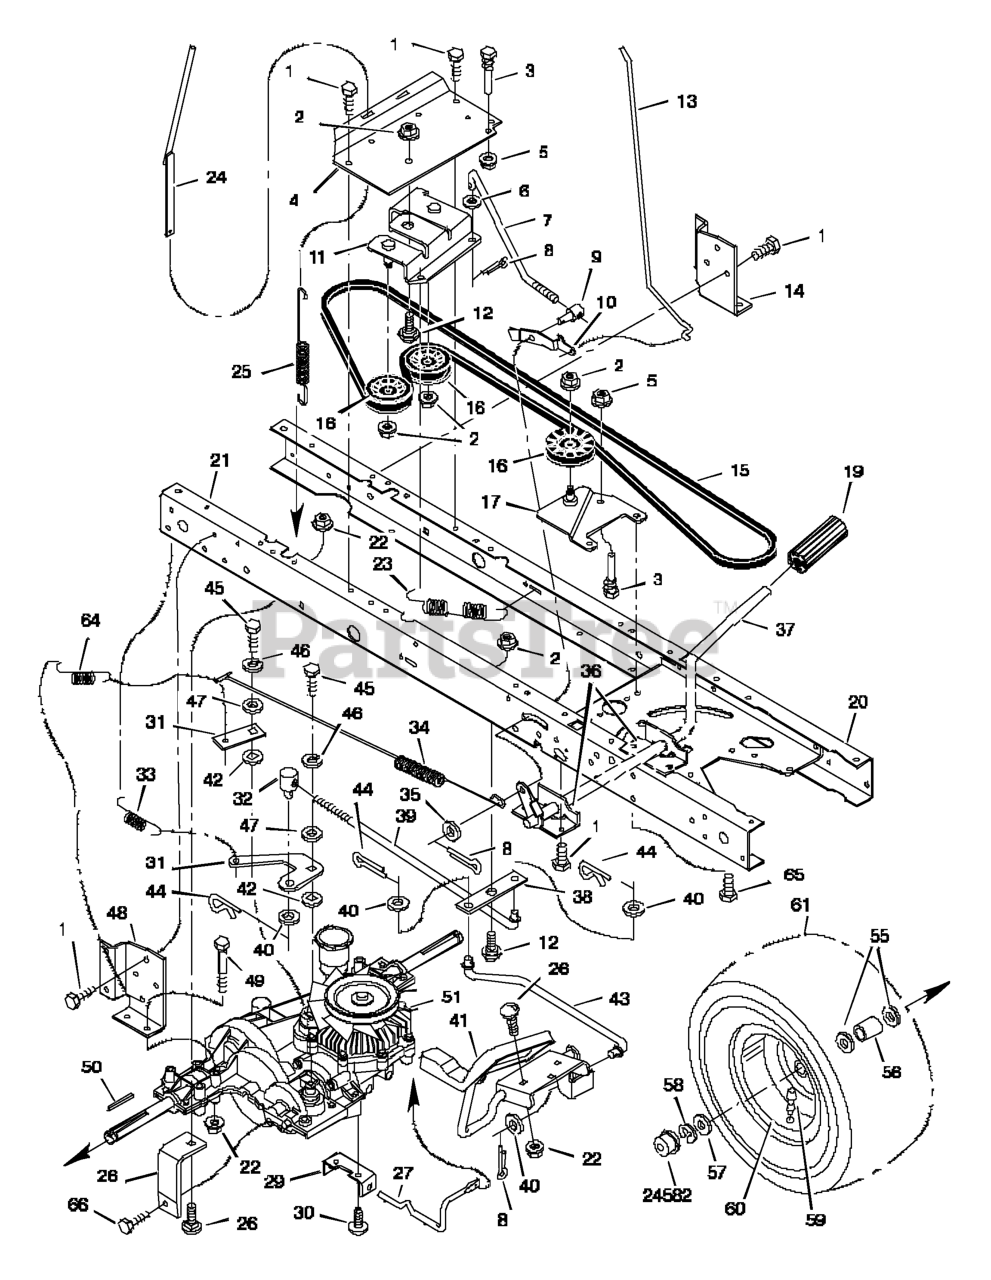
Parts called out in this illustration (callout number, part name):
2	Nut, Flange
3	Guide, Belt
4	Bracket, Idler
5	Locknut
6	Washer
7	Rod, Clutch
8	Pin, Cotter
9	Adjuster
10	Latch, Parking Brake
11	Bracket Assembly, Idler
12	Bolt, Shoulder
13	Rod, Parking Brake
14	Bracket, Transaxle
16	Pulley, Idler
17	Bracket Assembly, Idler
18	Pulley, Idler
19	Pedal
20	Frame, Left
21	Frame, Right
22	Nut, Flange
23	Spring, Extension
24	Lever Assembly, Tow Valve
25	Spring, Extension
26	Bolt, Carriage
27	Rod, Dump Valve
28	Strap, Right Torque
29	Bracket, Dump Valve
31	Arm, Brake
32	NUT, Adjusting, 1/2-13
33	Spring, Extension
34	Spring, Extension
35	Washer
36	Bracket, Pivot
37	Lever, Clutch/Brake
38	Bellcrank
39	Rod, Pedal Link - Rear
41	Pedal, Speed Control
43	Rod, Pedal Link - Front
44	Pin, Hair
46	Lockwasher
48	Bracket, Right Transaxle
49	Bolt
50	Key, Square
51	Transaxle **
59	Valve Stem
60	Wheel & Tire Assembly
62	Cap, Hub
63	Control Arm
64	Spring, Extension
24582	HUB CAP
